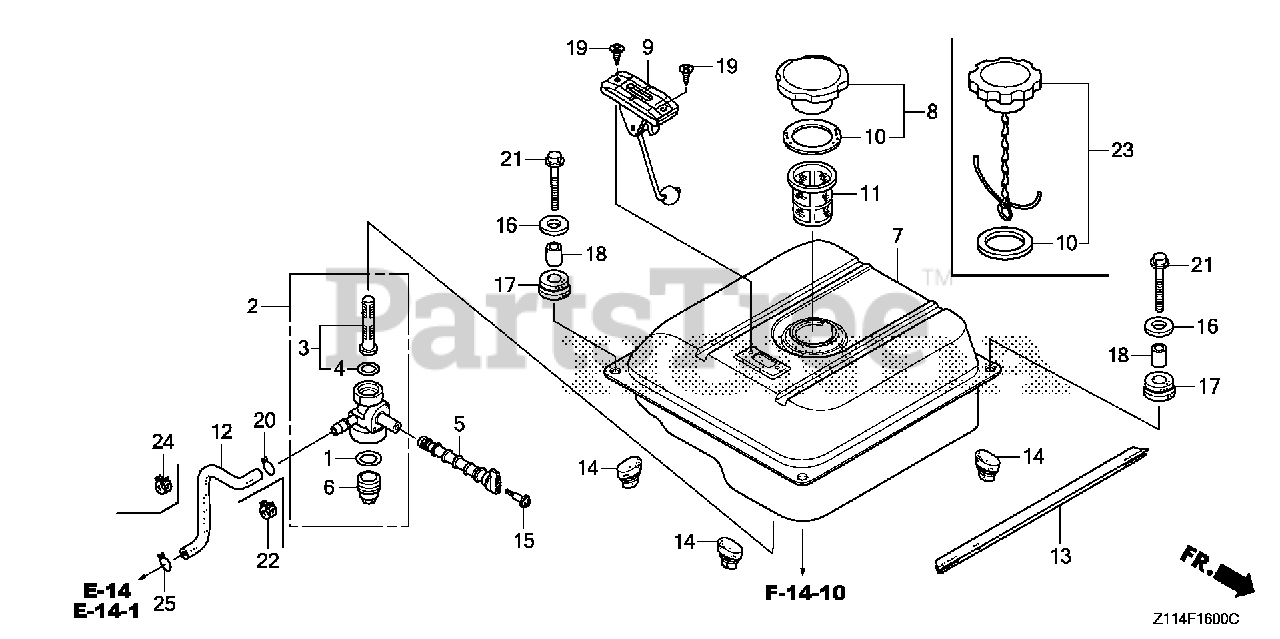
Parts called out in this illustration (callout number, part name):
1	GASKET, FUEL STRAINER CUP
2	PETCOCK ASSY.
3	SCREEN SET, FUEL STRAINER
4	O-RING (9.0X1.3)
5	LEVER, PETCOCK
6	CUP, FUEL STRAINER
7	TANK, FUEL *R280* (POWER RED)
8	CAP, FUEL FILLER
9	METER ASSY., FUEL
10	GASKET, FUEL FILLER CAP
11	FILTER, FUEL
12	TUBE, FUEL TANK (FKM) (ENGINE NO.)
12	TUBE, FUEL TANK (ENGINE NO.)
13	SEAL, FR. SEPARATOR
14	STOPPER, DISCHARGE GUARD
15	SCREW, PAN (4X19)
16	WASHER (6MM)
17	RUBBER, TANK CUSHION
18	COLLAR, TANK CUSHION
19	SCREW, FLAT (5X10)
20	CLIP, TUBE (B8) (ENGINE NO.)
21	BOLT, FLANGE (6X22)
22	CLAMP, TUBE (D8) (ENGINE NO.)
24	CLAMP, TUBE (D8) (ENGINE NO.)
25	CLIP, TUBE (B8) (ENGINE NO.)
